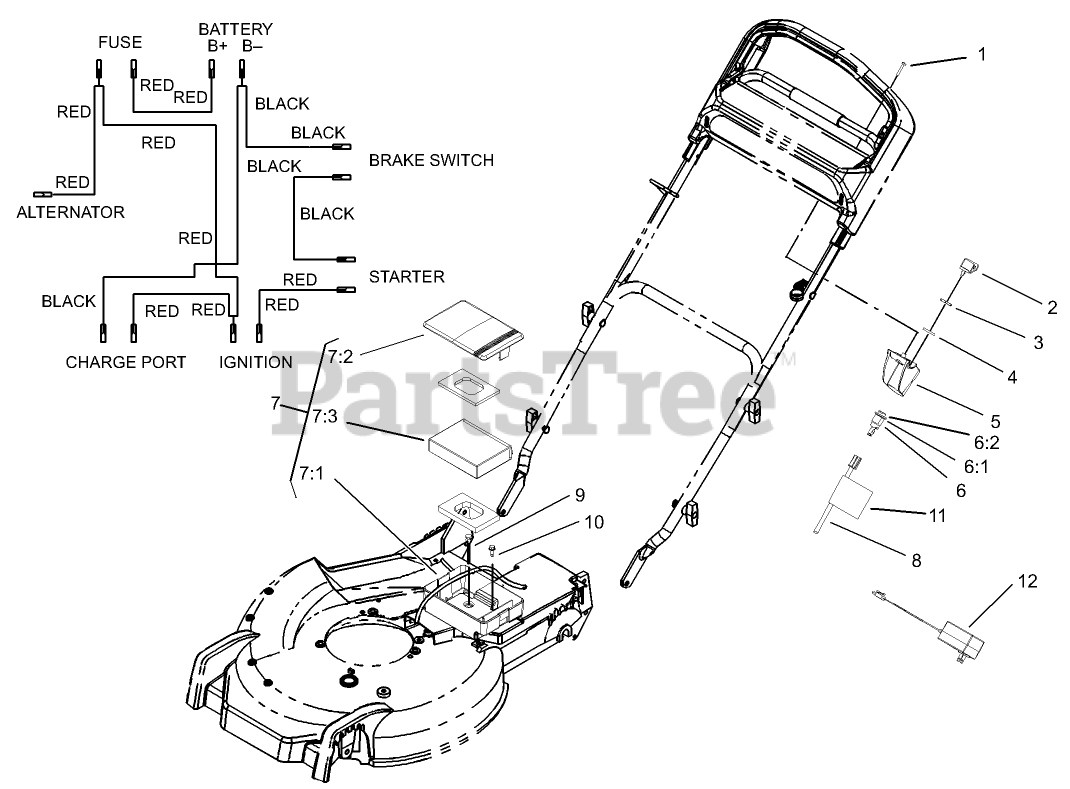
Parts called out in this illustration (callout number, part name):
1	SCREW-PPH, PLASTITE
2	KEY-IGNITION
5	SWITCH-HOLDER
6	STARTER SWITCH ASM
6:1	WASHER-LOCK
6:2	NUT-HH
7:1	BOX-BATTERY
7:2	COVER-BATTERY
8	HARNESS-WIRE, TC
9	SCREW-SPECIAL
11	DECAL-WARNING
12	CHARGER-EUROPEAN, 12V DC
